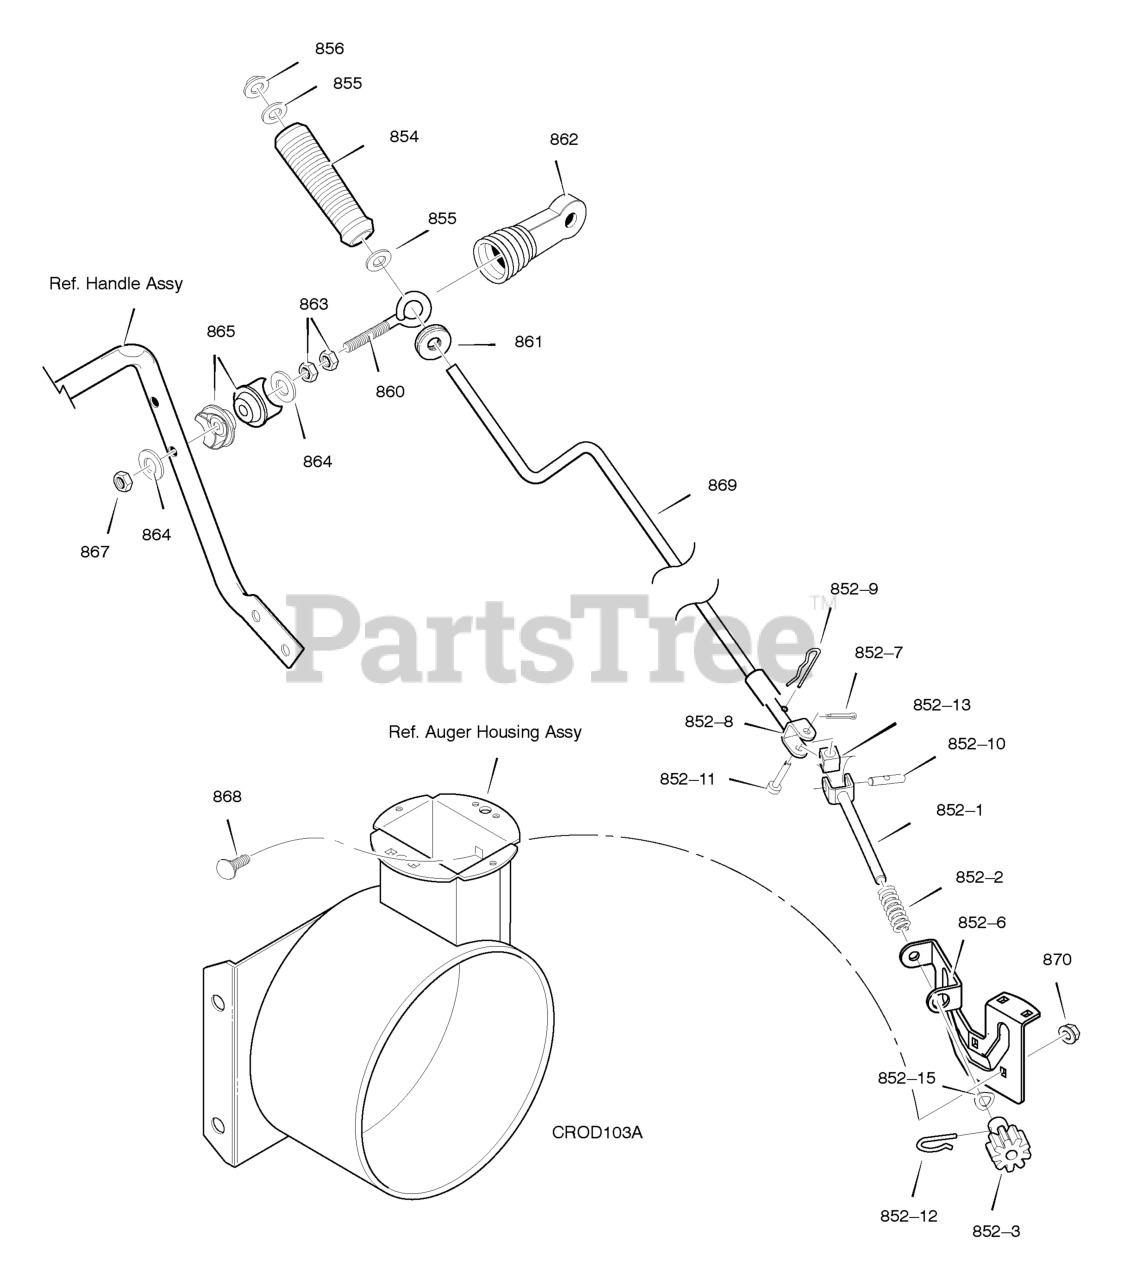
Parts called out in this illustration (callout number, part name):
852-1	ASSEMBLY, YOKE & ROD
852-2	SPRING, COMPRESSION
852-3	GEAR, CHUTE ROTATION 9T
852-6	BRACKET, GEAR MOUNT
852-7	PIN, COTTER
852-8	ASSEMBLY, YOKE ADAPTER YZ
852-9	PIN, HAIR
852-10	PIN, UNIVERSAL JOINT
852-11	PIN, CLEVIS
852-12	PIN, HAIR
852-13	HOUSING, UNIVERSAL
852-15	WASHER, SPRING
855	FLATWASHER
856	NUT, PUSH ON 3/8"
860	EYE BOLT 3/8-16X6.50
861	GROMMET, EYE BOLT
862	BOOT, EYE BOLT
863	NUT, 3/8-16 HEXJAM
864	FLATWASHER .406X.81X.066
865	ADAPTER, BOOT (2 REQUIRED)
867	NUT, 3/8-16 HEXNYL
868	BOLT, CARRIAGE 1/4-20 X 1.00
869	CRANK, ASSY CHUTE
870	NUT, 1/4-20 NYLOCK
